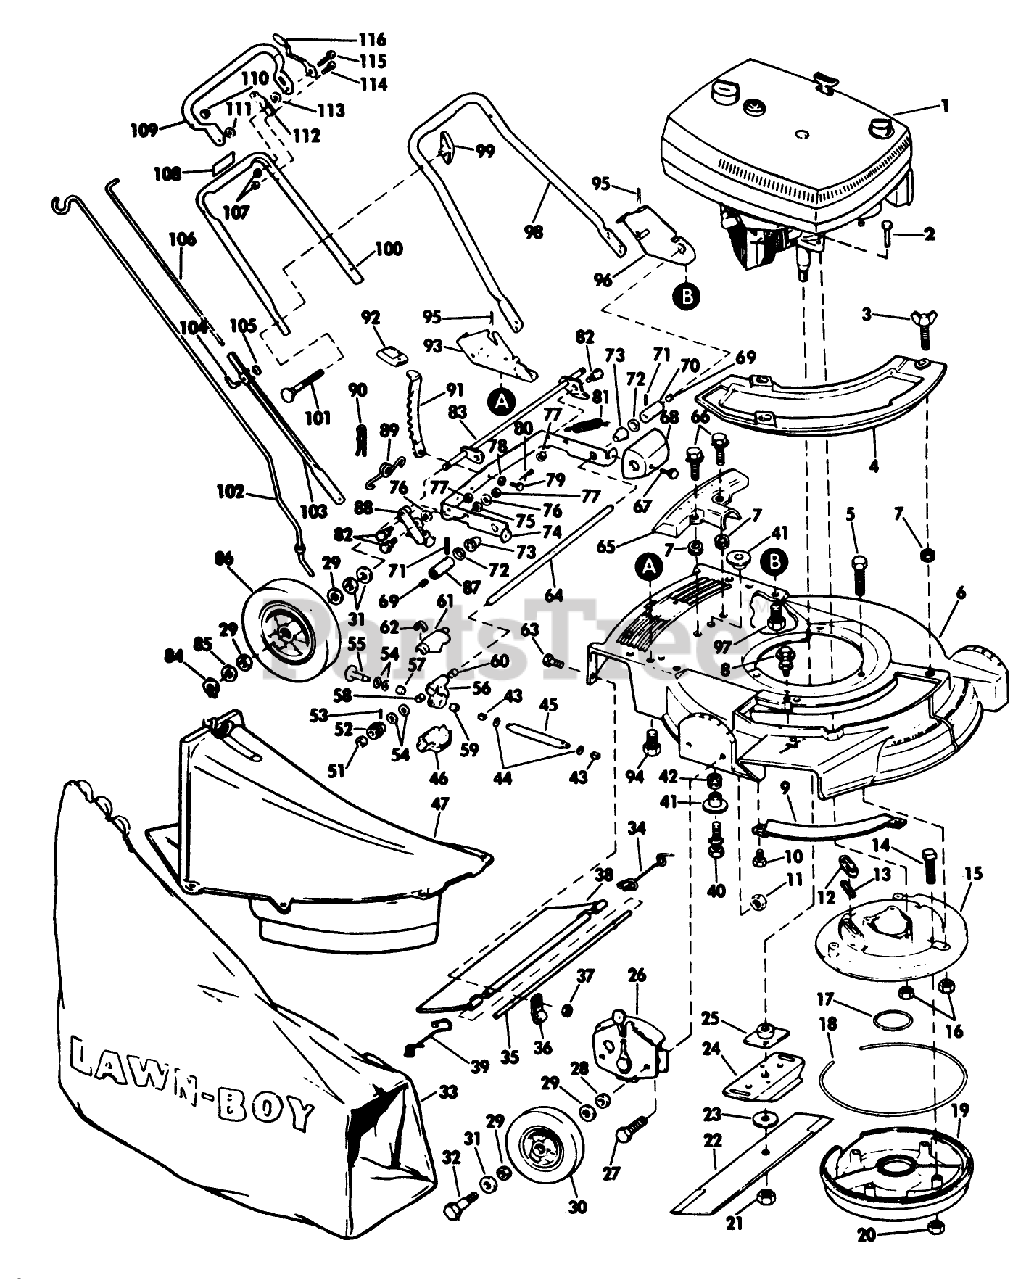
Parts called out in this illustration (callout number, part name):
1	See Page 26 for Engine, Magneto and Carburetor Parst List. See Note #2 at bottom of this page.
2	BOLT F
3	WING SCREW LAWRE
4	ROD CONTROL
5	SCREW V
9	BAR-TOE
11	NUT
12	SLEEVE
13	GASKET S
14	SCREW
16	NUT-LOCK F
18	Gasket Muffler (outside)
20	LOCKNUT E
21	NUT-BLADE
27	Screw
28	WASHER WROUGHT
29	Washer-Felt
30	WHEEL & TIRE KIT
32	BOLT WHEEL
33	ORD LB 89802 WHOLE GOODS
34	SPRIG T/SHLD ASOC
35	ROD 21" ADVANCE
36	CLAMP ROD KMC
39	SPRING;TRAILING SHIELD RH
41	SPACER ECK PRES
42	GROMMET
43	BUSHING
44	O Ring
51	WASHER
53	ROLL PIN
54	THRUST WASHER
57	Needle Bearing
61	GEAR COVER UPPER
64	DRIVE SHFT TAG AY
65	COVER
66	SCREW SEMS TRM HEX HD
68	GUARD
69	GREASE PLUG
71	PIN
76	WASHER S
77	STOP NUT
78	WASHER SPRING LAR
79	PIN
81	SPRING
82	BOLT RB&W
83	Axle Assembly
84	RET RING
85	SPACER
89	SPRING N.A.S
91	LEVER
92	KNOB
94	SCREW
95	HAIR PIN
97	SCREW
99	NUT-WING
100	HANDLE
102	ROD GRASSBAG
106	ROD CONTROL
111	WASHER M
115	BOLT RB&W
116	KNOB & SPRING
